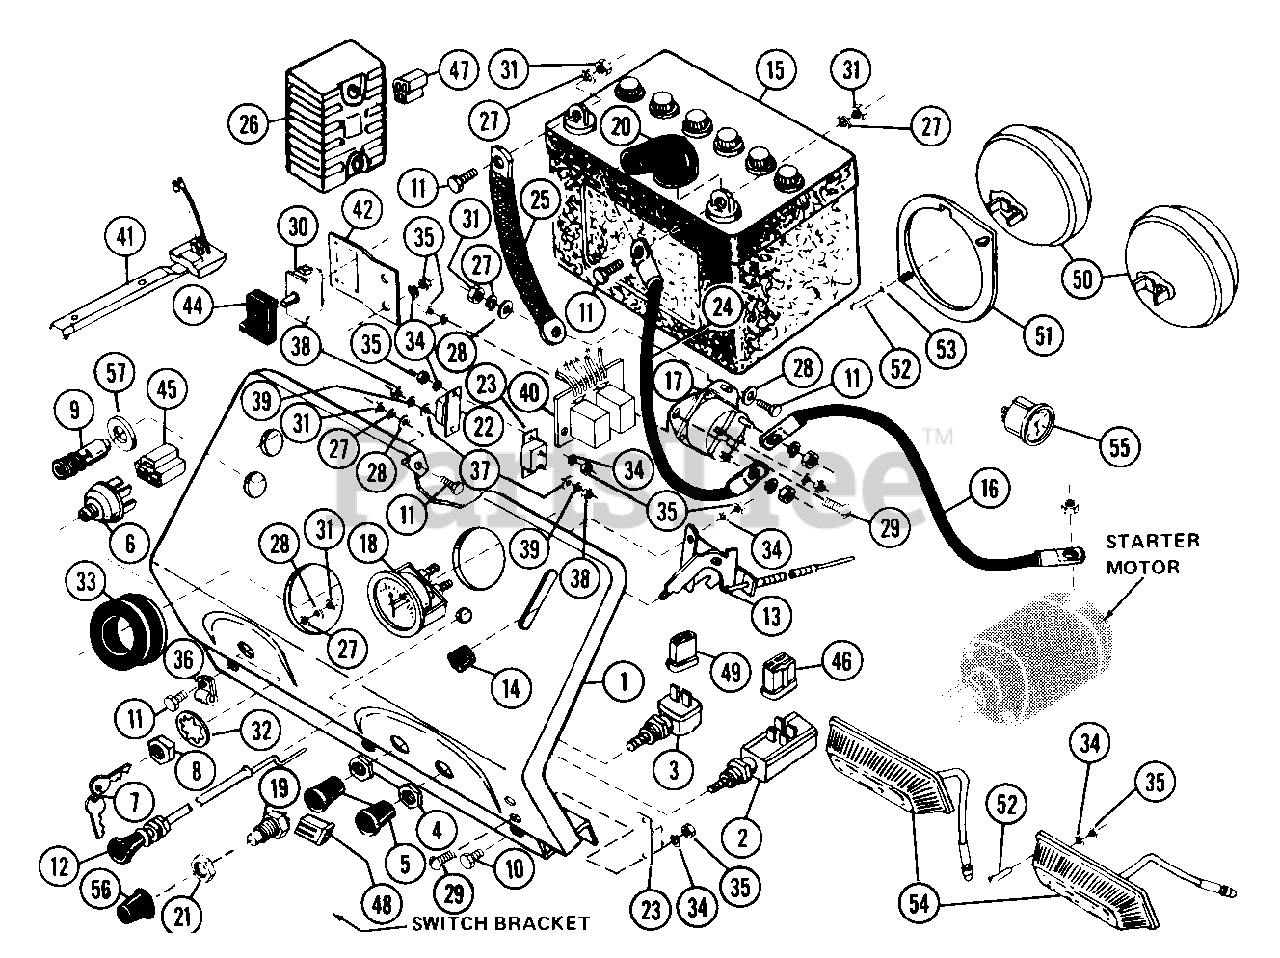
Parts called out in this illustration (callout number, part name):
1	DASH ASSEMBLY
1	CYLINDER ASSEMBLY (SHORT)
2	CLUTCH SWITCH
3	LIGHT SWITCH
4	NUT .50-20 PL
5	KNOB
6	IGNITION SWITCH
7	KEYS
8	NUT .562-24
9	P.T.O. INDICATOR & WIRE
9	PTO INDICATOR LIGHT
10	SCR-TAP 10-16X.50 HWH PL AB
11	BLT-HEX .25-20X.75 PL GR2
12	CHOKE CONTROL
13	THROTTLE CONTROL
15	BATTERY
16	GROUND CABLE .31X22.00X.31
17	SOLENOID
18	AMMETER
19	SAFETY SWITCH
19	SWITCH-NEUTRAL START N.O.
20	INSULATOR
21	NUT-HEX .625-32 PL
21	NUT- .562-18
22	CIRCUIT BREAKER
23	CIRCUIT BREAKER
25	GROUND CABLE
26	REGULATOR RECTIFIER
27	WSHR-LK .250X.077 HVY PL
28	WSHR-FL-STL.281X.62X.065 PL
29	SCR-MCH 10-24X.50 SLRH PL
31	NUT-HEX .250-20 PL
32	WSHR-LK-INT .563X.040 PL
33	GROMMET
34	WSHR-LK 10X.047 MED PL
35	NUT-HEX 10-24 PL
37	WSHR-FL-STL .219X.500X.049 PL
38	NUT 10-32 PL
39	WSHR-LK 10X.047 MED PL
40	INTERLOCK MODULE ASSY
40	INTERLOCK MODULE
41	SWITCH SEAT
42	SWITCH BRACKET
44	SWITCH BOOT
45	CONNECTOR HOUSING
46	CONNECTOR
47	CONNECTOR
48	CONNECTOR
49	CONNECTOR
50	HEAD LIGHT
51	HEAD LIGHT RETAINER RING
52	SCR-MCH 10-24X.50 SLTR PL
53	WSHR-FL-STL .250X.562X.049 PL
54	TAIL LIGHT
55	HOUR METER
57	SPACER .510X.670X.100X1.000
